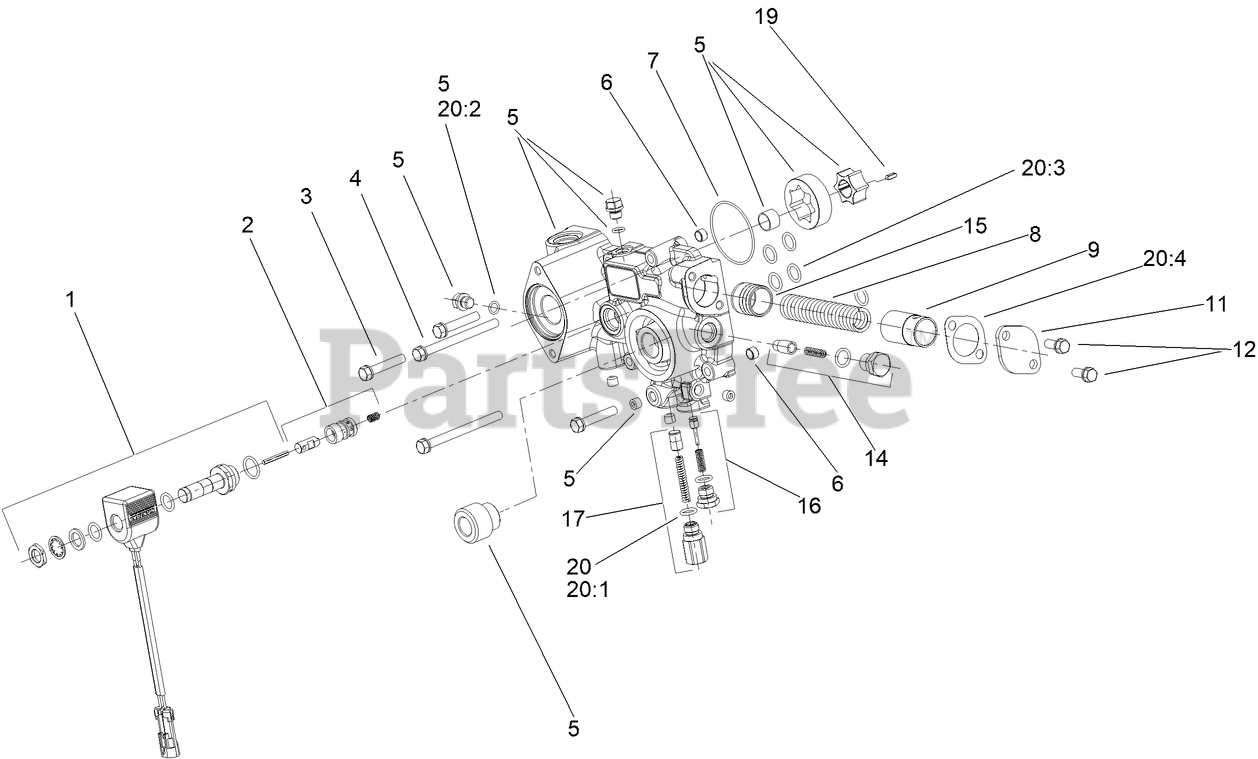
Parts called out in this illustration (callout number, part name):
1	SOLENOID ASM
2	SOLENOID VALVE ASM
5	PUMP BODY ASM
8	SPRING-COMPRESSION
12	BOLT AND WASHER ASM
14	FILTER BYPASS VALVE ASM
16	CHARGE RELIEF VALVE ASM
17	PRESSURE VALVE ASM
20	CHARGE PUMP SEAL KIT
20:2	O RING-PLUG
20:3	Packing
